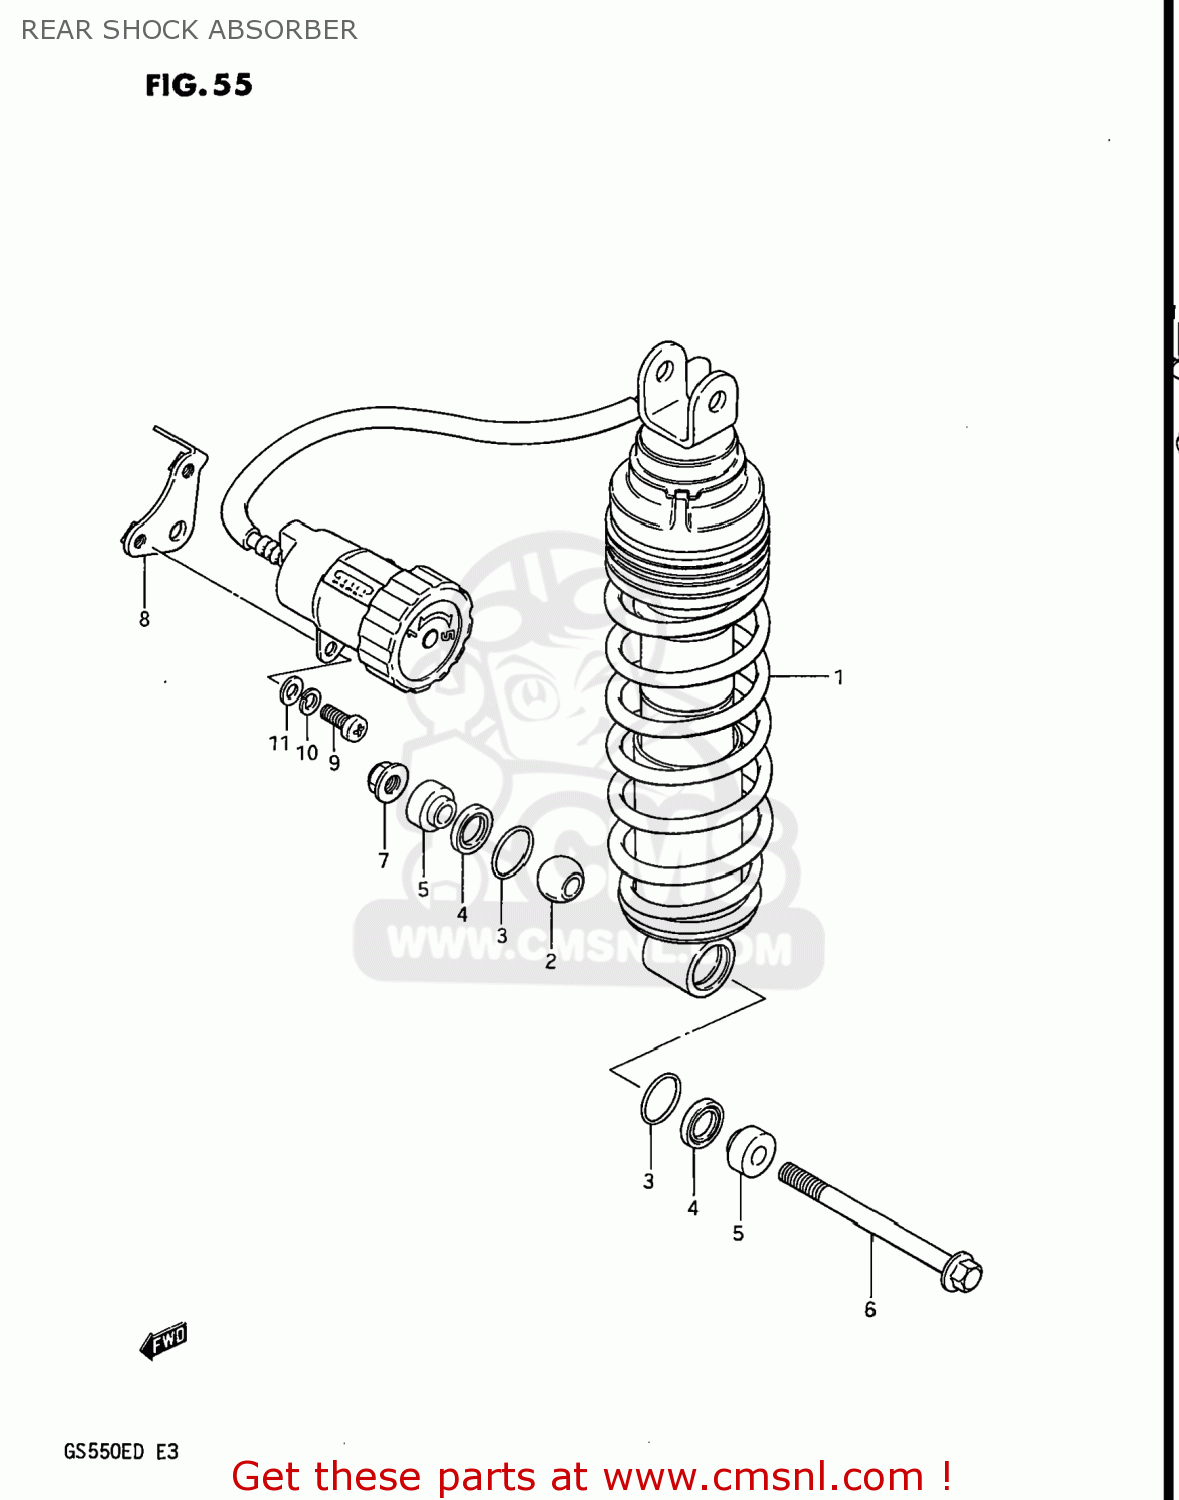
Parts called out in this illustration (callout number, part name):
1	ABSORBER ASSEMBLY,REAR SHOCK
2	BEARING(10X24X15)
3	RING
4	SEAL,DUST
5	COLLAR
6	BOLT(10X115)
7	NUT
8	BRACKET,RESERVOIR TANK
9	SCREW
10	LOCK WASHER
11	WASHER
